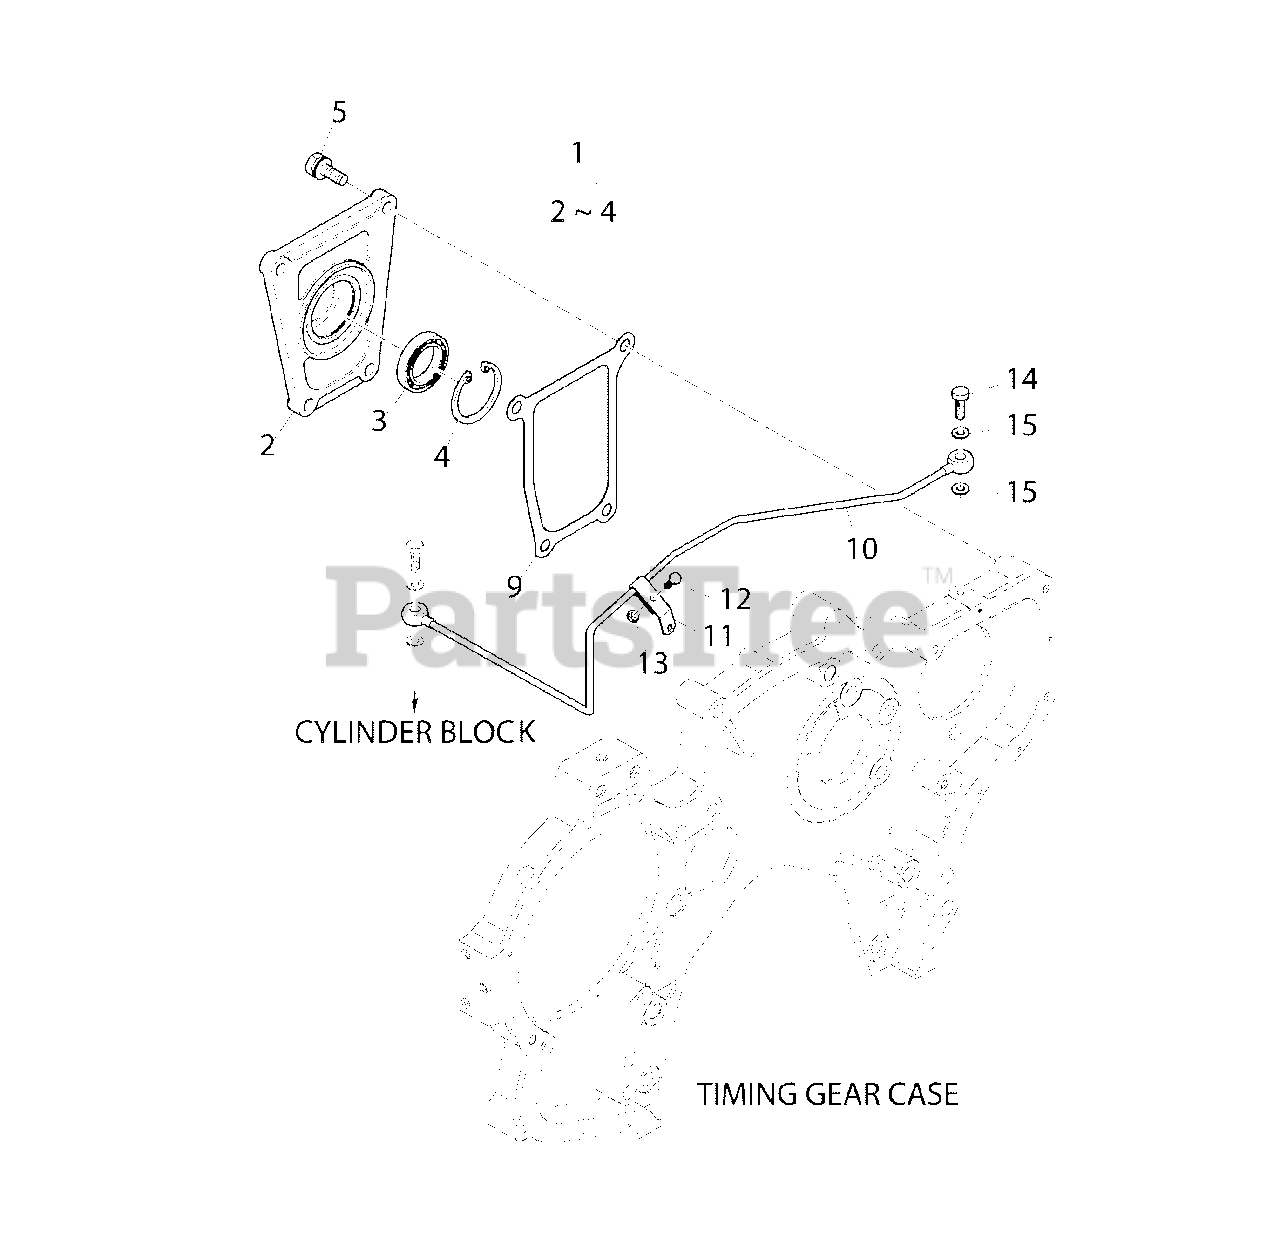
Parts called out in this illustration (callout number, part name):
1	* END COVER
2	* END COVER
3	* BEARING, BALL
4	* RING, SNAP
5	* BOLT
9	* GASKET, AIR COMPRESSOR
10	* PIPE, OIL
11	* CLIP
12	* BOLT, HEX
13	* NUT, HEX
14	* SCREW
15	* RING, SEAL
